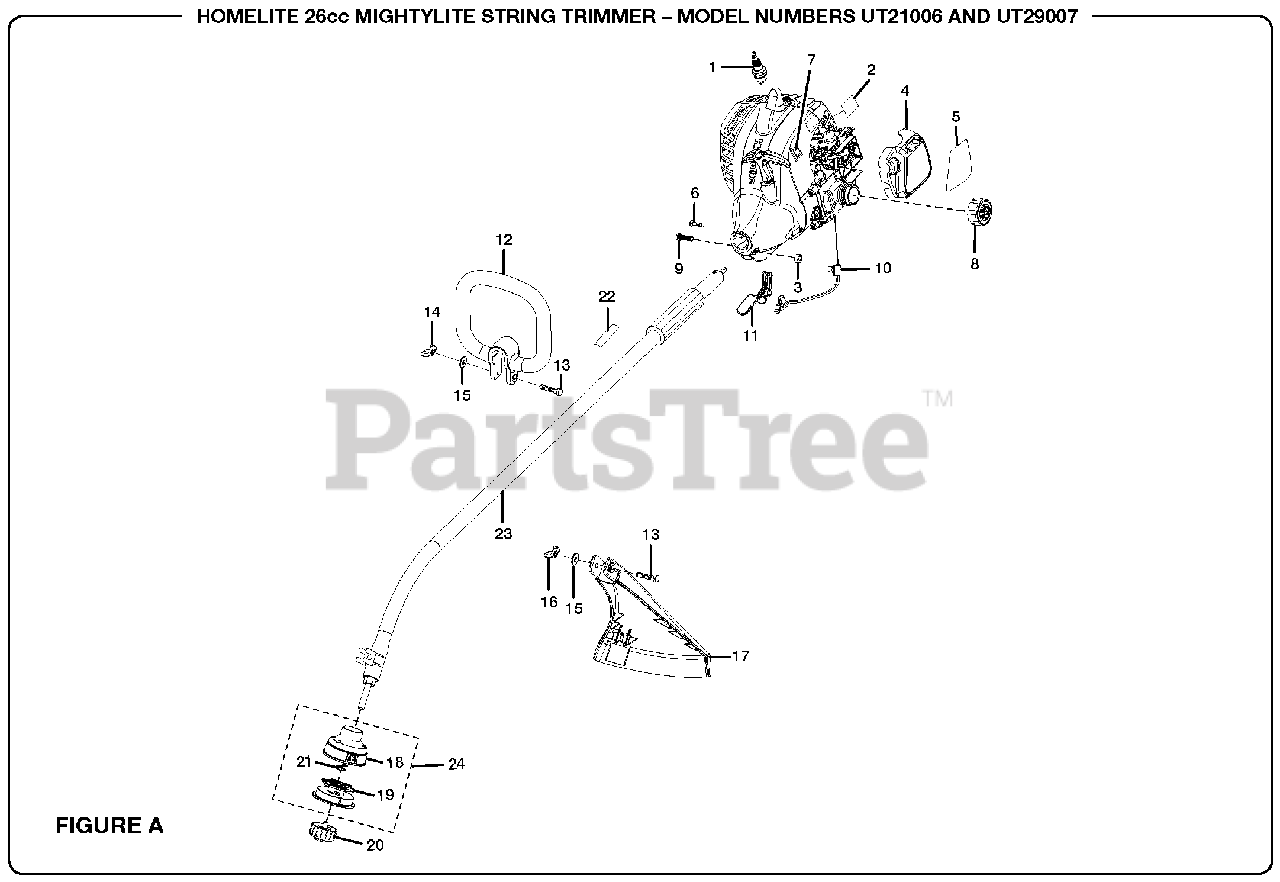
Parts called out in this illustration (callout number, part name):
1	Spark Plug (Champion RCJ6Y)
2	Logo Label
3	Hex Nut (M6)
4	Air Box Cover
5	Starting Label
6	Screw (8-16 x 5/16 in.)
7	Switch
9	Bolt (M6 x 20 mm)
10	Throttle Cable
11	Throttle Trigger
13	Bolt (1/4-20 x 45 mm)
14	Wing Nut (1/4-20)
15	Washer (1/4-20)
16	Wing Nut (1/4-20)
17	Curved Shaft Grass Deflector
18	Dual String Head Housing
19	Dual Line Spool and String
20	Spool Retainer
21	Spring
22	Warning Label
23	Boom Assembly
24	String Head Assembly (Incl. Key Nos. 18, 19, 21)
